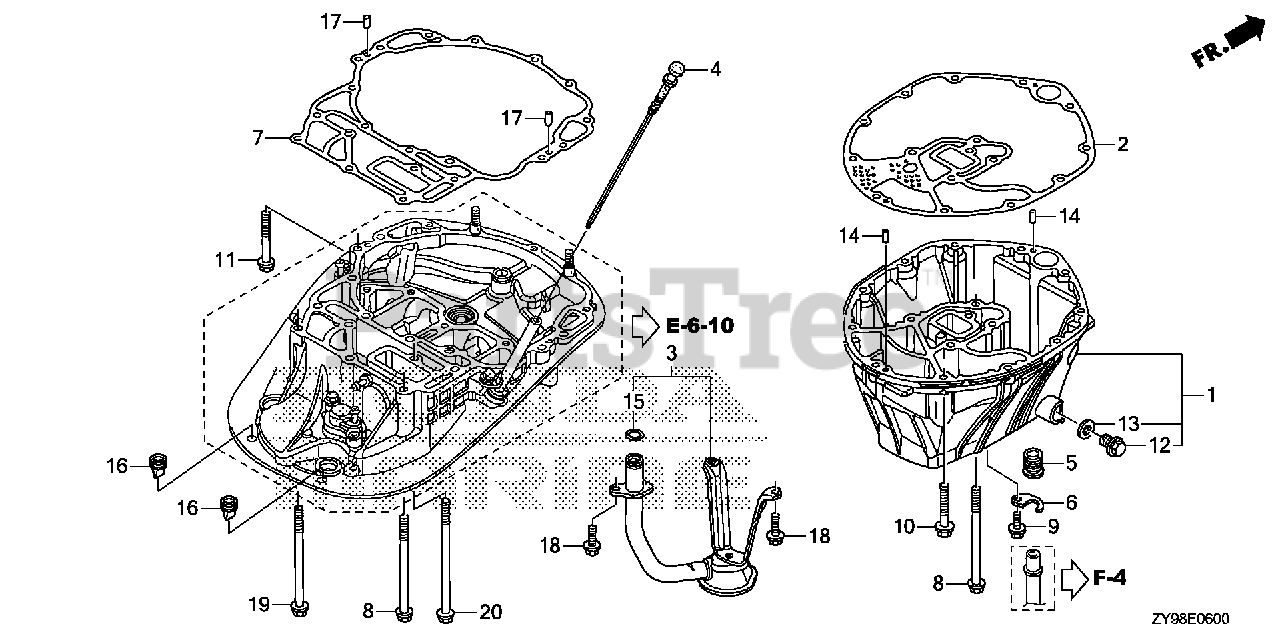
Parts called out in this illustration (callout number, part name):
1	CASE ASSY., OIL *TGRAY* (GRAY)
2	GASKET, OIL PAN
3	STRAINER, OIL
4	DIPSTICK, OIL
5	GROMMET, WATER TUBE
6	PLATE, WATER TUBE
7	GASKET, MOUNT CASE
8	BOLT, FLANGE (8X100)
9	BOLT, FLANGE (6X12)
10	BOLT, FLANGE (8X35)
11	BOLT, FLANGE (8X45)
12	BOLT, DRAIN PLUG
13	WASHER, DRAIN PLUG (12MM)
14	PIN, DOWEL (6X10)
15	O-RING (15.5X2.7)
16	GROMMET (1WAY)
17	PIN, DOWEL (6X10)
18	BOLT, FLANGE (6X16)
19	BOLT, FLANGE (8X100)
20	BOLT, FLANGE (8X120)
